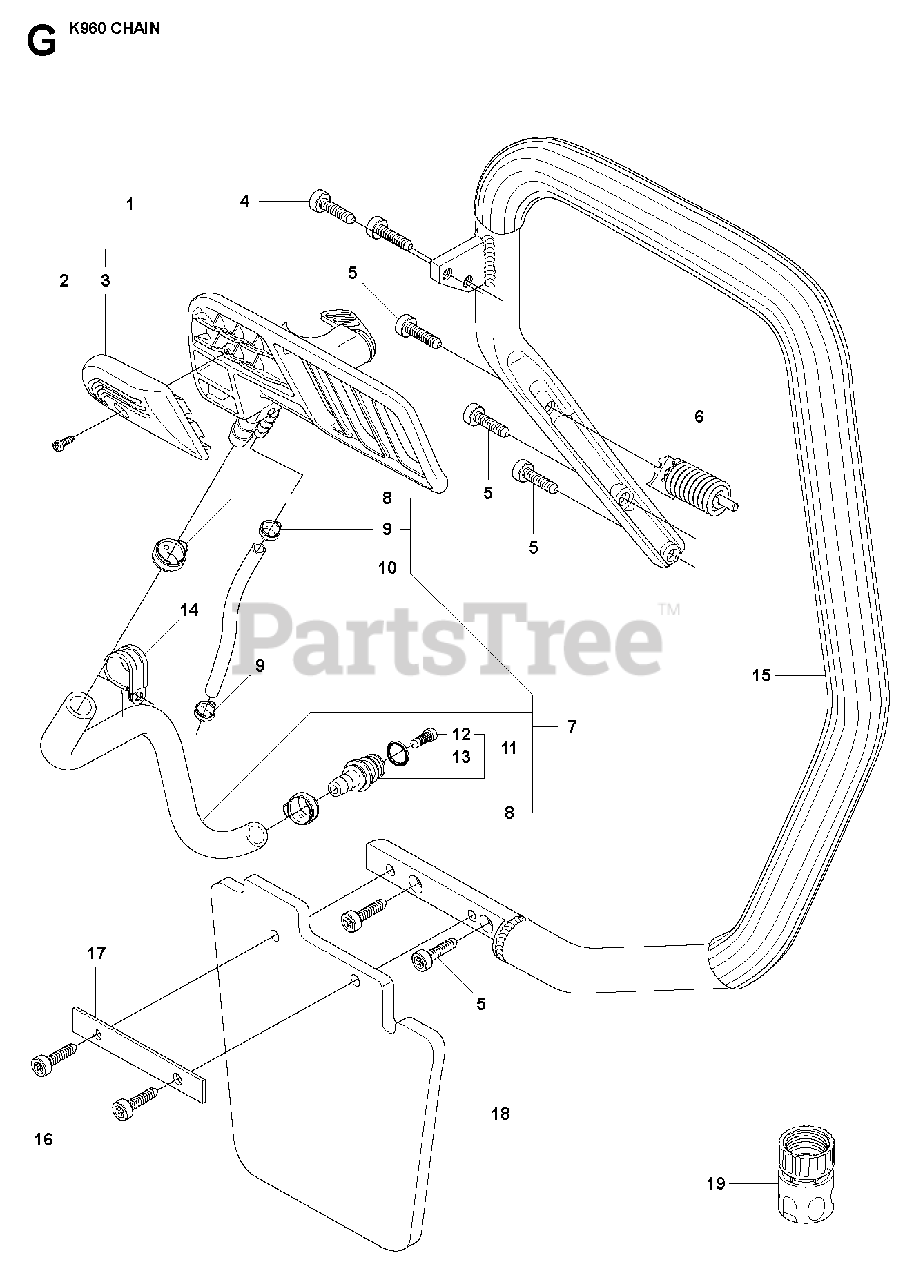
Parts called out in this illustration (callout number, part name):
2	SCREW CCRPANT
4	SCREW ITXSCT
5	SCREW ITXSCT
6	ANTIVIBRATION ELEMENT
8	HOSE CLAMP
11	NIPPLEIncl. 12, 13
13	O-RING
16	SCREW ITXSCM
19	COUPLER"3/4"""
